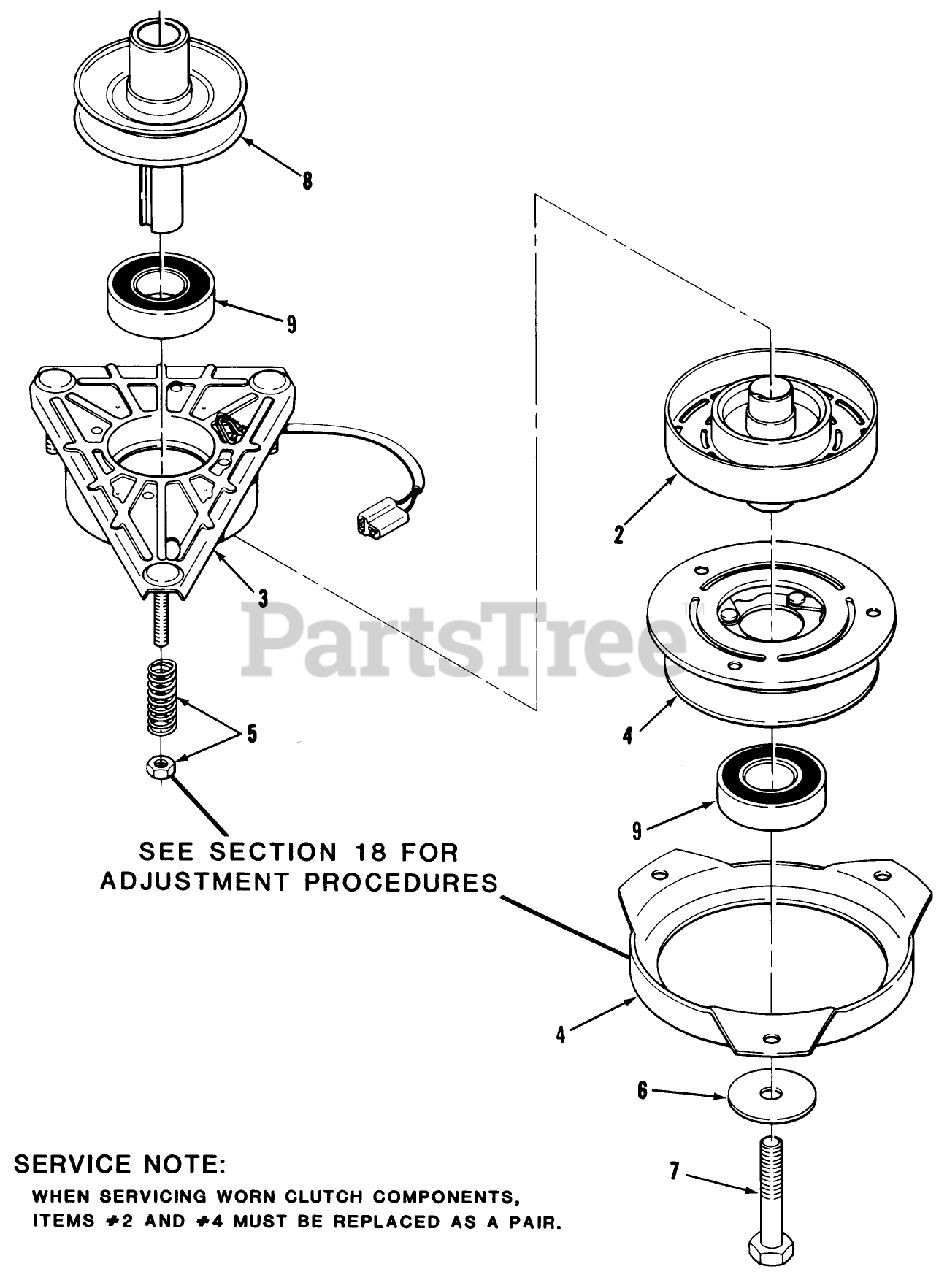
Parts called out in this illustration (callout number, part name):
1	Electric Clutch Assy (includes items 2, 3, 4 5)
4	ASS'Y-ARMATURE
5	ACCESS SPRING & NUT
6	WASHER
8	PULLEY-ENGINE
9	BEARING-ELEC CLUTCH
